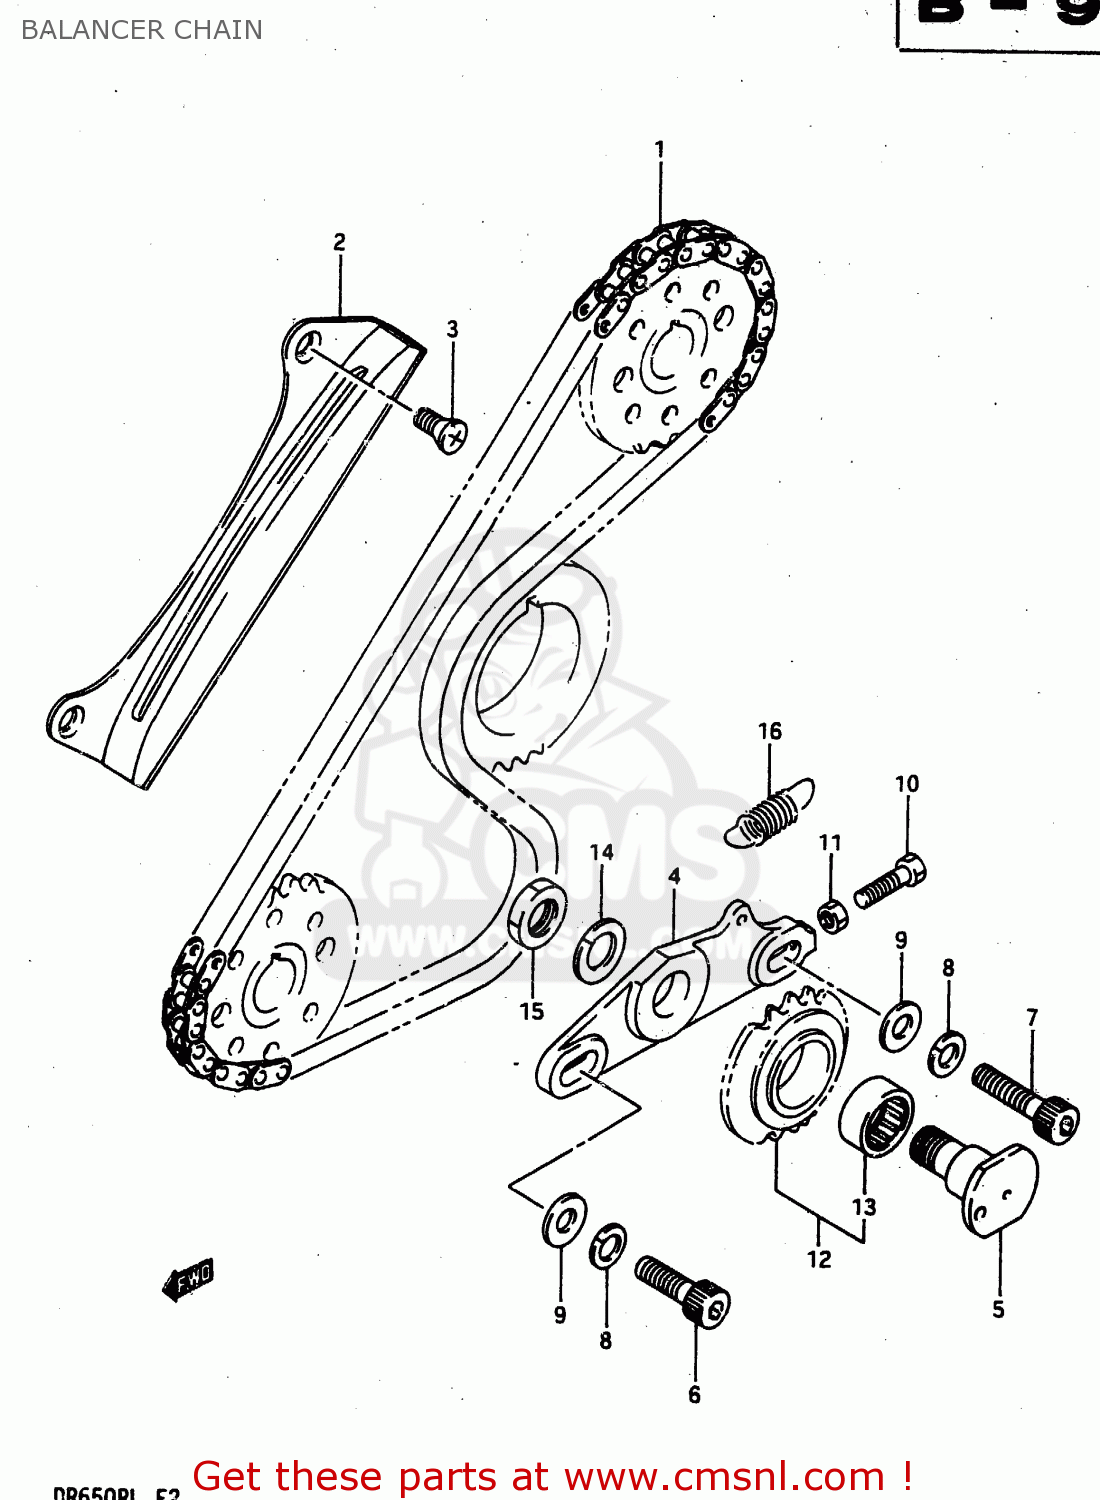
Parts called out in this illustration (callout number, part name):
1	GOVERNOR ASSEMBLY,EXHAUST
2	GUIDE,BALANCER CHAIN
3	SCREW M6X1X16
4	BRACKET,BALANCER CHAIN
5	SHAFT,BALANCER CHAIN TENSIONER
6	BOLT(8X22)
7	BOLT, REAR (8X30)
8	LOCK WASHER
9	WASHER
10	BOLT 5X20
11	NUT
12	SPRKT,BALANCER CHAIN TENSIONER
13	BEARING(17X23X12)
14	WASHER,LOCK 12
15	NUT
16	SPRING
